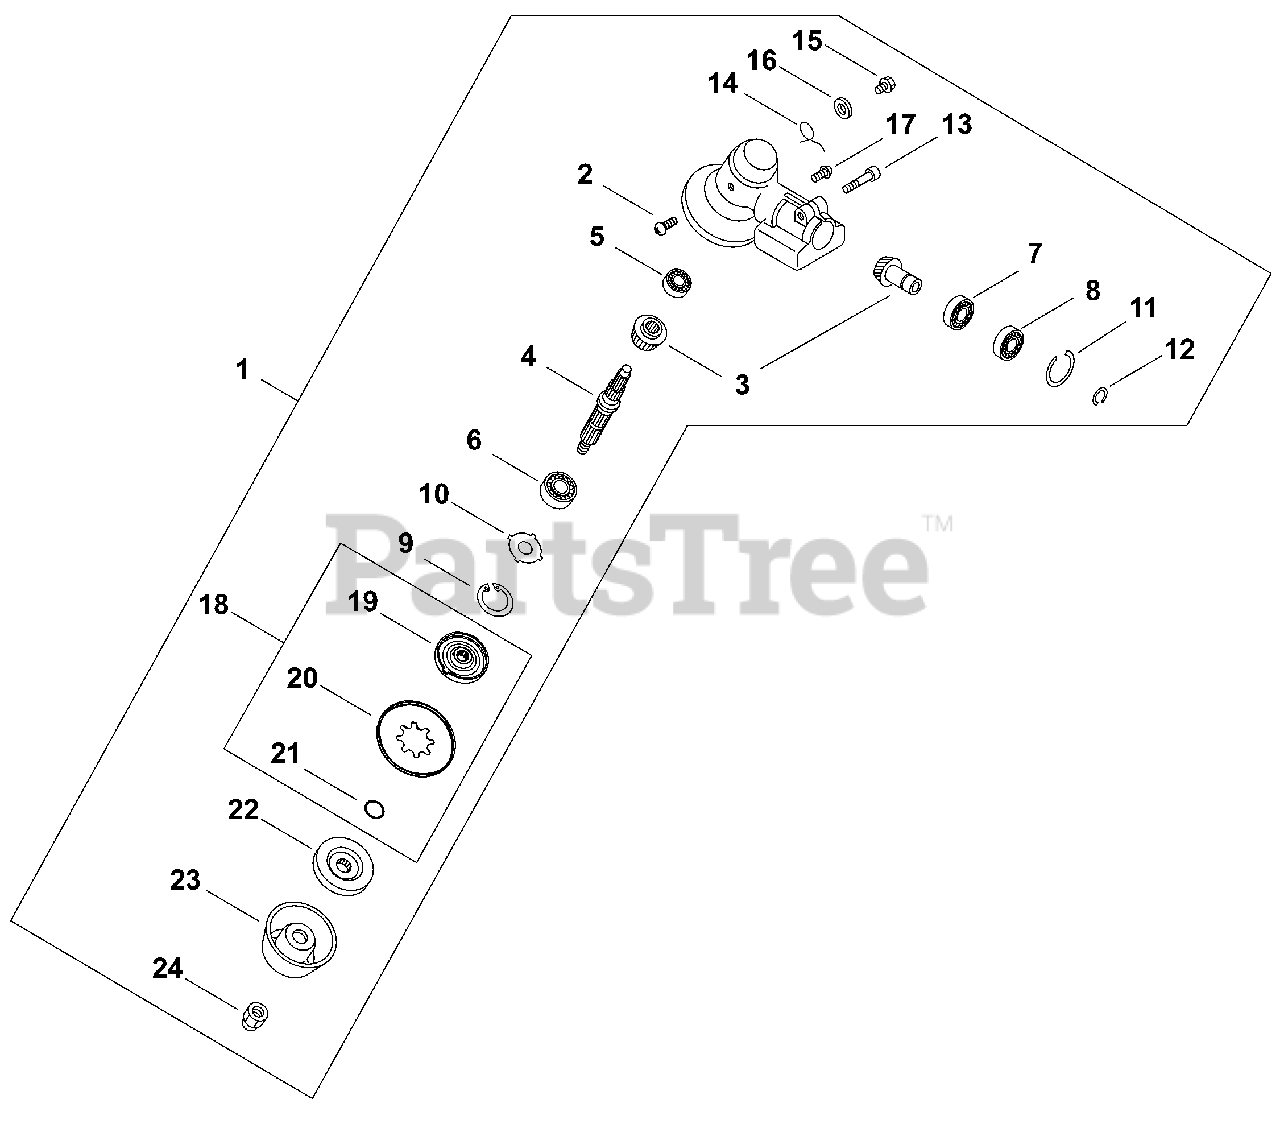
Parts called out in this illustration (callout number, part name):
1	GEAR CASE ASSY
2	SCREW 4×6
3	GEAR SET
4	SHAFT, GEAR
5	BEARING, BALL 629
6	BEARING, BALL 6201
7	BEARING, BALL 6001
8	BEARING, BALL 6001Z
9	RING, SNAP Ø32
11	RING, SNAP 28
12	RING, SNAP 12
13	BOLT 6×30
14	SPRING, TORSION
15	BOLT M8×8
16	WASHER 8.5×18×0.8T
17	SCREW 5×10
18	RETAINER, BLADE
19	PLATE, ADAPTOR
20	PLATE, ADAPTOR - LOWER
21	O-RING 12 MM
22	PLATE, ADAPTOR - LOWER
24	NUT, LOCK - NYLON INSERT
